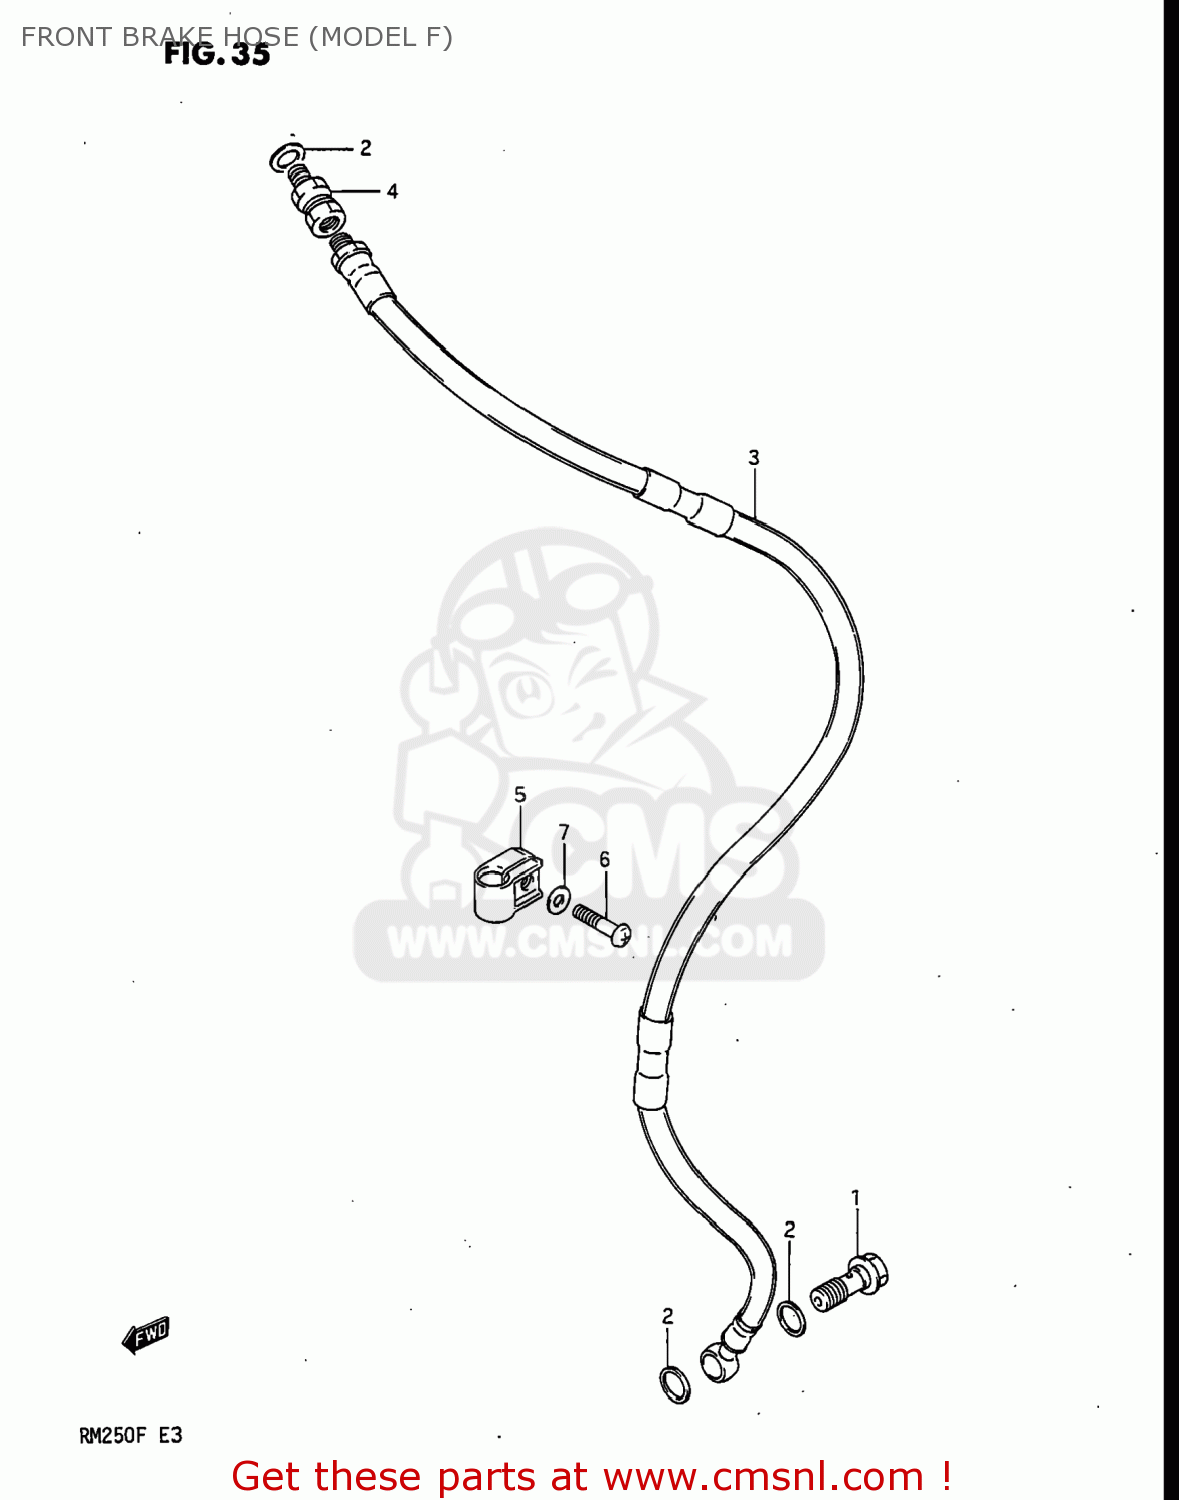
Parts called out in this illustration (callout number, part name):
1	BOLT UNION
2	WASHER(10X15X1.5)
3	HOSE,FRONT BRAKE
4	ADAPTER,BRAKE HOSE
5	CLAMP,FRONT BRAKE HOSE
6	SCREW
7	WASHER
